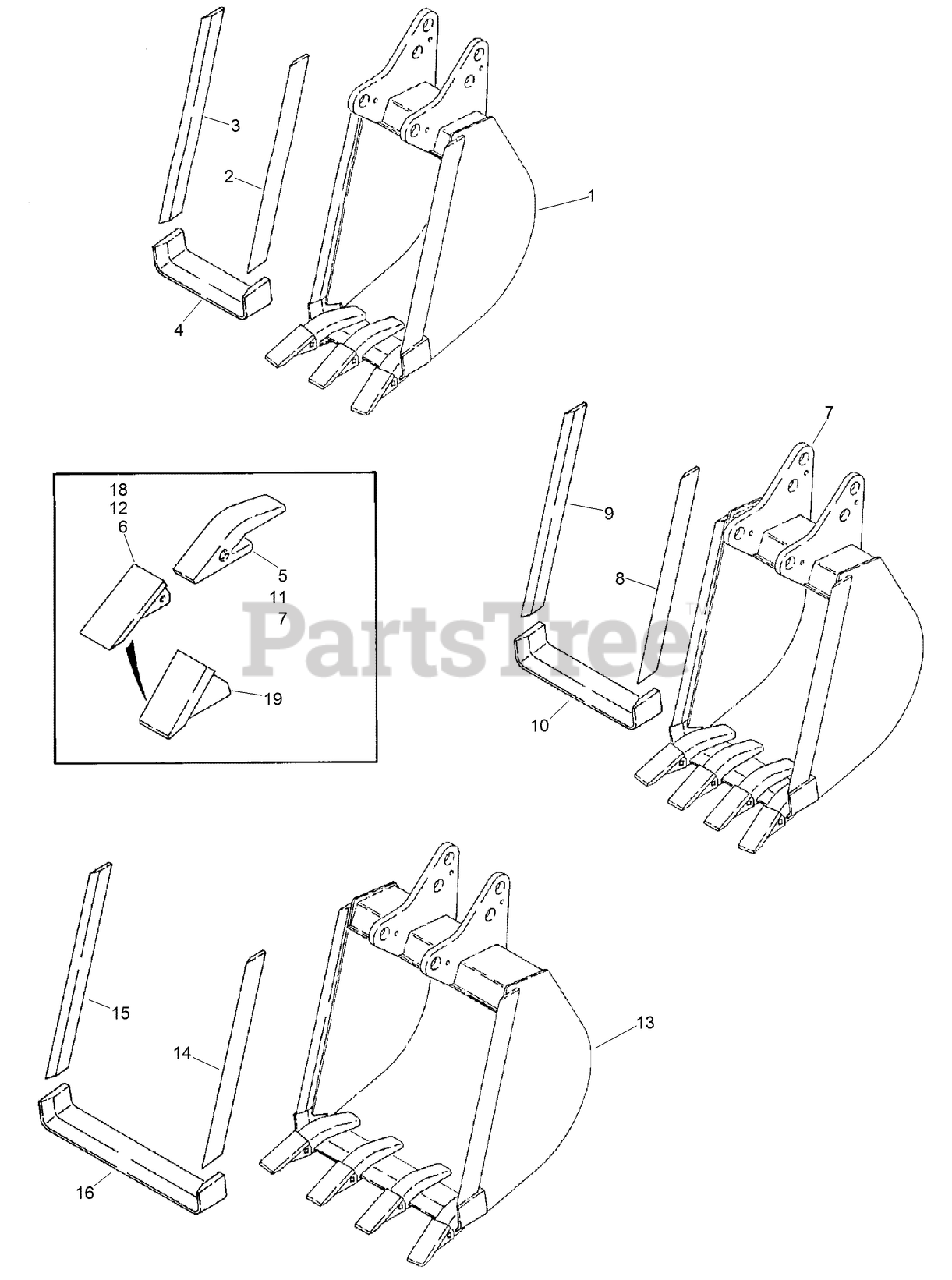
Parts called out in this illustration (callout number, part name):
1	ASSEMBLY - Bucket, 344 mm (13 in) (Includes items 2 - 6 )
2	EDGE-CUTTING - LH
3	EDGE-CUTTING - RH
5	SHANK - Bucket Tooth
6	POINT - Bucket Tooth
7	BUCKET-TRENCHING, 18IN
8	EDGE-CUTTING - LH
9	EDGE-CUTTING - RH
11	SHANK - Bucket Tooth
12	POINT - Bucket Tooth
13	ASSEMBLY - Bucket, 610 mm (24 in) (Includes items 14 - 18)
14	EDGE-CUTTING - LH
15	EDGE-CUTTING - RH
18	POINT - Bucket Tooth
19	POINT - Bucket Tooth, Heavy Duty (Service Option Only)
